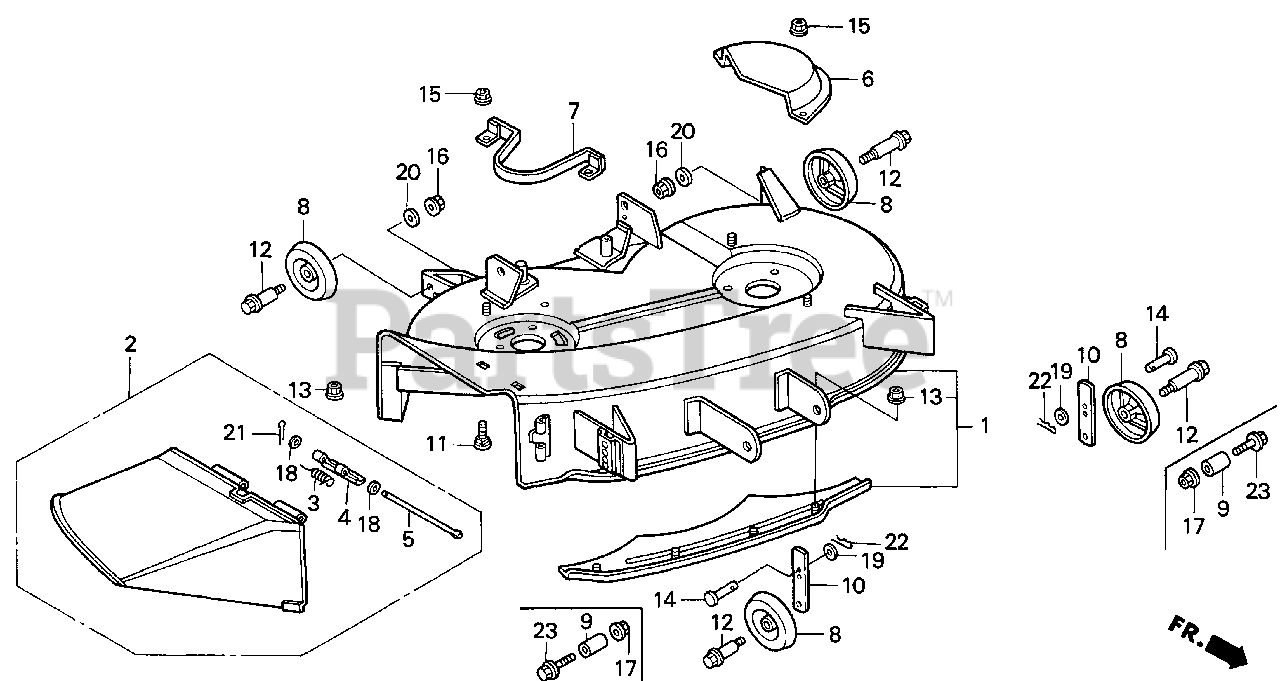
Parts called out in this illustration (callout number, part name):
1	HOUSING, CUTTER
2	ADAPTER, DISCHARGE
3	SPRING, DISCHARGE ADAPTER
4	HINGE, DISCHARGE ADAPTER
5	PIN, DISCHARGE ADAPTER (NA USE ALT:06814-V09-A01)
6	COVER, L. BELT
7	STOPPER, BELT
8	ROLLER, ANTI-SCALP
9	COLLAR, ANTI-SCALP ROLLER (12.7X15.9X39.5)
10	ARM, ROLLER
11	BOLT, SPECIAL (9X15)
12	BOLT, ANTI-SCALP ROLLER
13	NUT, FLANGE (8MM)
14	PIN, ROLLER ARM (8X22)
15	NUT, FLANGE (8MM)
16	NUT, FLANGE (10MM)
17	NUT, FLANGE (12MM)
18	WASHER, PLAIN (6MM)
19	WASHER, PLAIN (8MM)
20	WASHER, FLAT (10MM)
21	PIN, COTTER (2.0X15)
22	PIN, SNAP (7MM)
22	PIN, LOCK (8MM)
23	BOLT, FLANGE (12X60)
